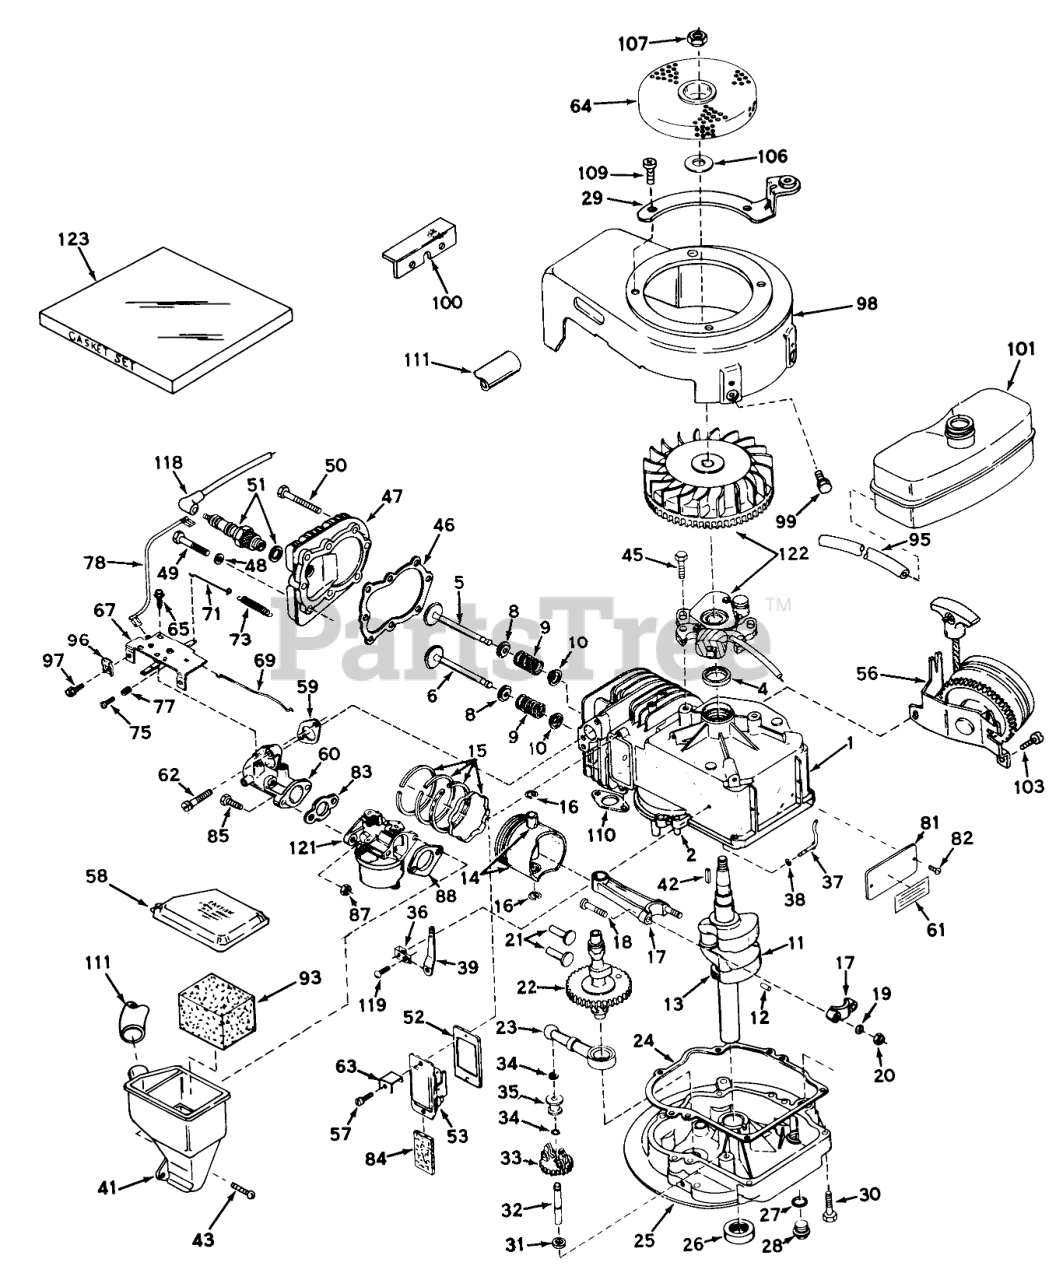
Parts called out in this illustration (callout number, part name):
1	Cylinder Assy. (Incl. Nos.2 & 4)
2	Pin-Dowel
4	OIL SEAL
5	Valve, Intake (Std.)(Incl. Nos.8, 9 & 10)
5	Valve, Intake (1/32" oversize)(Incl. Nos. 8, 9 & 10)
6	Valve, Exhaust (Std.)(Incl. Nos. 8, 9 & 10)
6	Valve, Exhaust (1/32" oversize)(Incl. Nos.8, 9 & 10)
8	Cap-Upper Valve Spring
9	Spring-Valve
10	Cap-Valve, Spring
11	Crankshaft Assy. (Incl. Nos. 12 & 13)
12	Pin, Groove
13	Gear, Crankshaft
14	Piston & Pin Assy. (Std.)(Incl. 2 of No. 16)
14	Piston & Pin Assy.(.010 oversize)(Incl.2 of No. 16)
14	Piston & Pin Assy. (020 oversize)(Incl.2 of No. 16)
15	Ring Set, Piston (Std.)
15	Ring Set, Piston (.010 o.s.)
15	Ring Set, Piston (.020 o.s.)
16	Ring-Retaining, Piston Pin
17	Rod Assy., Connecting (Incl. Nos. 18, 19 & 20)
18	Bolt, Connecting
20	LOCKNUT
21	Lifter-Valve
22	Camshaft
23	Oil Pump ASM
24	Gasket, Mounting
25	Flange Assy., Mtg. (Incl. Nos. 26, 27, 28 & 32)
26	Seal Oil
27	Gasket-Oil Drain
28	Plug Oil Drain
29	Bracket Assy., Starter
30	Screw (1/4-20 x 1-1/4)
31	Washer-Flat
32	Shaft-Governor
33	Governor Gear ASM
34	Ring-Retaining
35	Spool-Governor
36	Clamp-Lever, Governor
37	Rod, Gov. (Incl. No.38)
38	Washer-Flat
39	Governor Lever
41	Body, Air Cleaner
42	Key Flywheel
43	Screw, Fil. Hd. Sems
46	Gasket-Cylinder Head
47	CYLINDER HEAD
49	Screw
50	Screw Hex Hd. Cap
51	SPARK PLUG
52	Gasket Breather
53	Breather Assy. (Incl. Nos. 52 & 84)
56	Starter, Side Mount
58	Cover, Air Cleaner
59	Gasket, Intake
60	Pipe, Intake
61	480B GIL SNWTHWR O/
62	Screw, Fil. Hd. Sems
63	Retainer Clip
64	Screen, Flywheel
65	Screw (10-24 x 9/16)
67	Depth Bar
69	Link, Throttle to Governor
71	Link-Governor
73	Spring, Governor
75	Screw
77	Spring-Compression
78	Wire, Ground
81	IDENTIFICATION PLATE
84	Element-Breather
85	Screw (1/4-28 x 7/8)
87	Nut and Lock Washer (1/4-28)
88	Gasket-Air Cleaner
93	Element, Air Cleaner
95	Line-Fuel (8.62)
96	Conduit
97	Screw (10-32 x 3/8)
98	Housing, Blower
99	Screw (1/4-20x19/32)
100	Bracket, Shroud
101	Tank, Fuel
103	Screw
106	Washer
107	Hex Nut
110	Gasket Exhaust
111	Tube, Air Cleaner
118	Cover-Spark Plug
119	Screw
121	Carburetor
122	Magneto
123	Gasket Set
